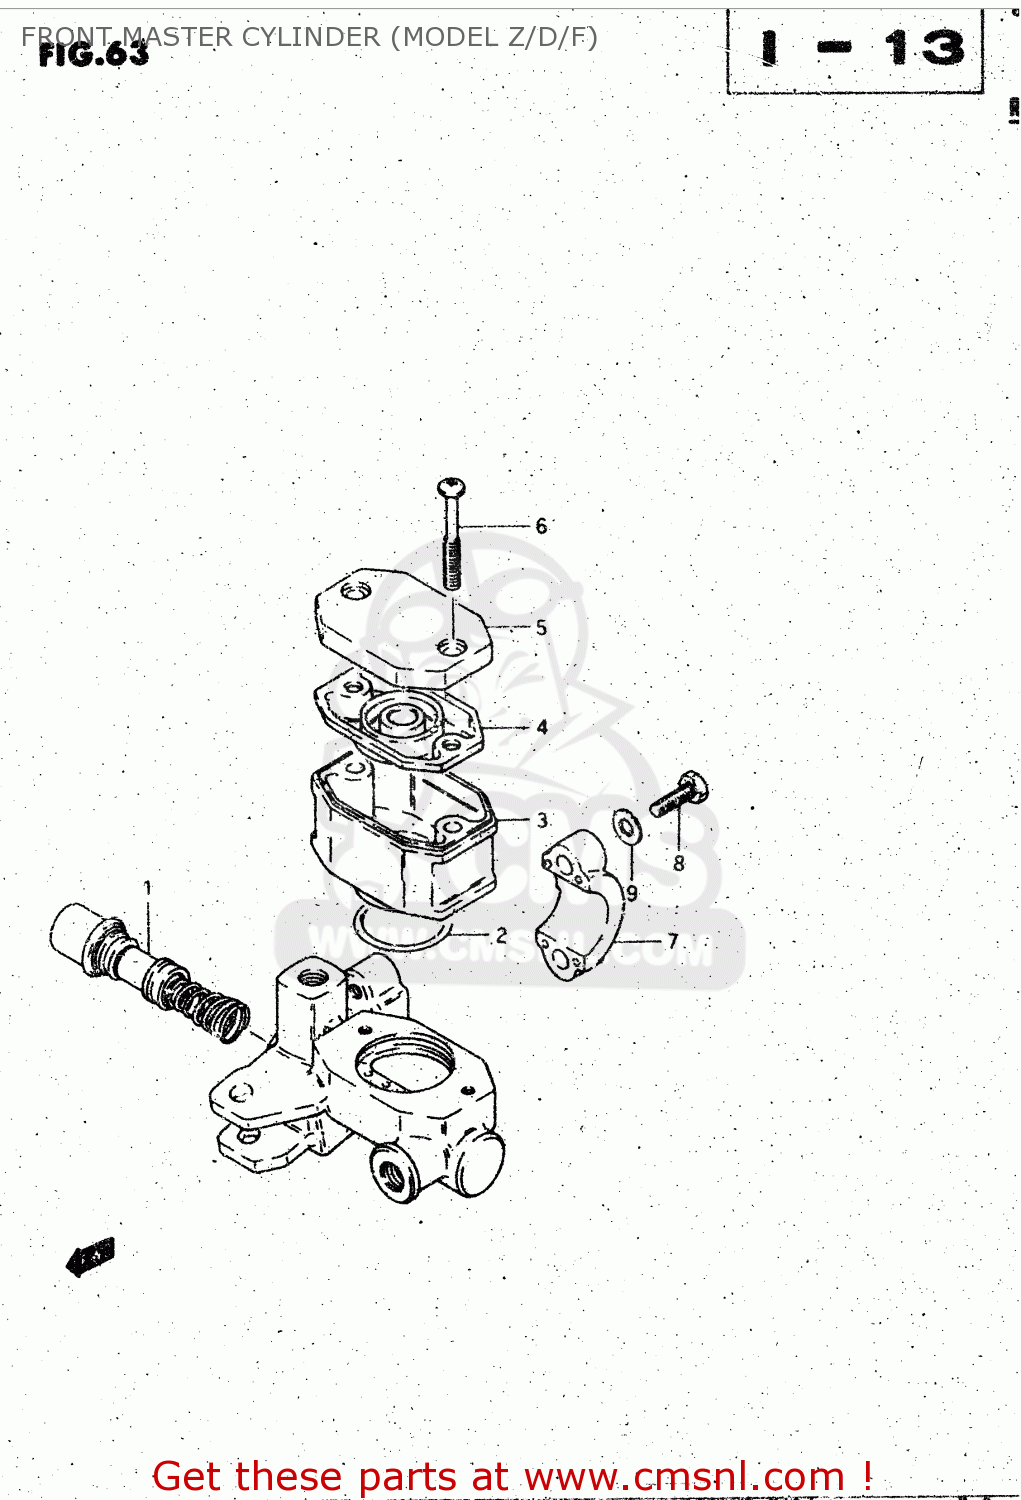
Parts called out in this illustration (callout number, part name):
1	PISTON & CUP SET
2	O RING
3	RESERVOIR
4	DIAPHRAGM
5	CAP
6	SCREW
7	HOLDER
8	BOLT
9	WASHER
